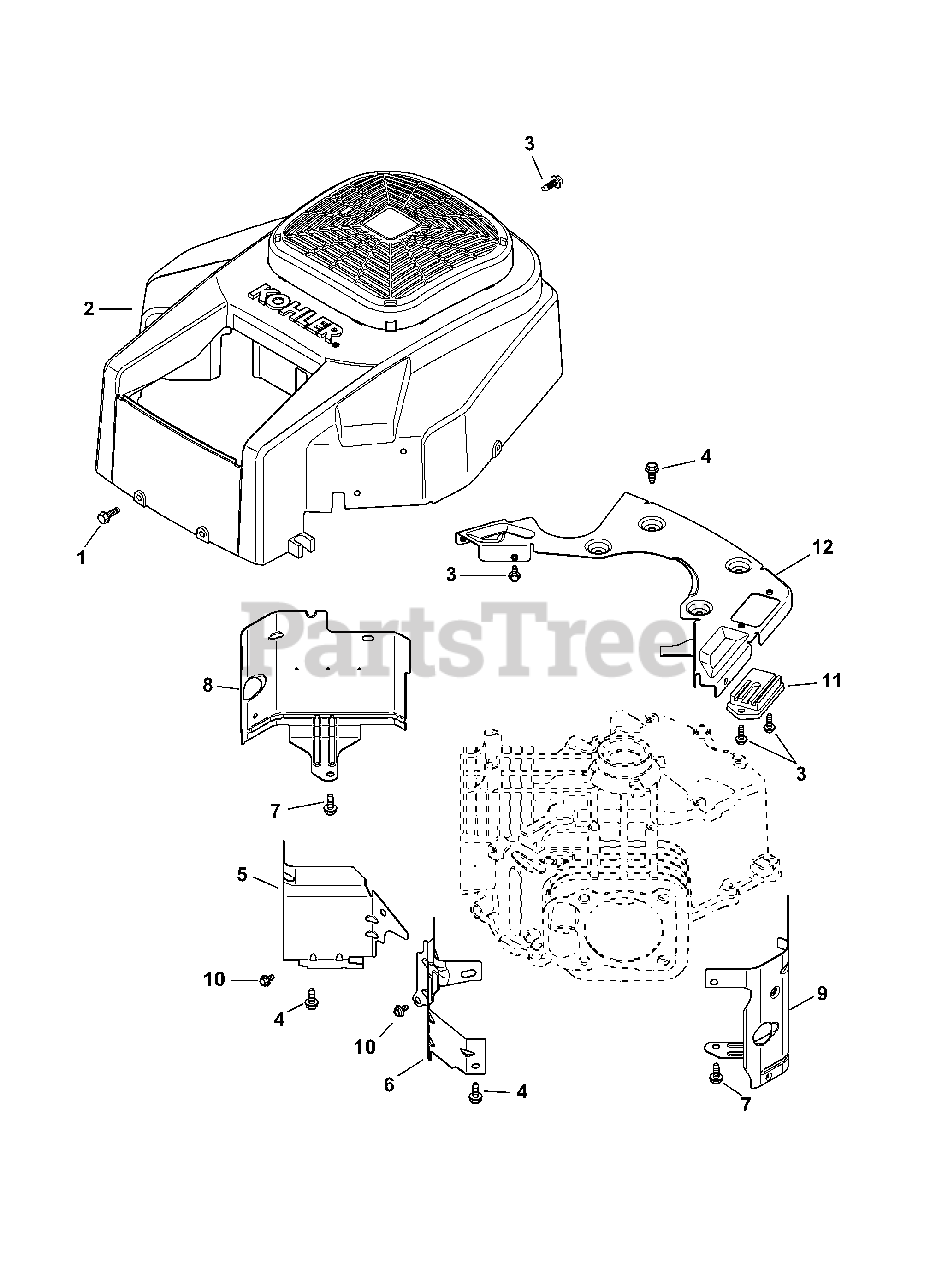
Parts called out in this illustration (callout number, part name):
1	Screw, M6 x 1.7 x 18
2	Blower Housing Kit
3	Flange Screw, M5 x .8 x 16
4	Flange Screw, M6 x 1.0 x 16
5	Valley Baffle, #1 Cylinder
6	Valley Baffle, #2 Cylinder
7	Flange Screw, M6 x 1.0 x 10
8	Cylinder Barrel Baffle, #1 Side
9	Cylinder Barrel Baffle, #2 Side
10	Flange Screw, M5 x .8 x 10
11	Regulator/Rectifier
12	Backing Plate Kit
NS	Fixed Guard Decal
